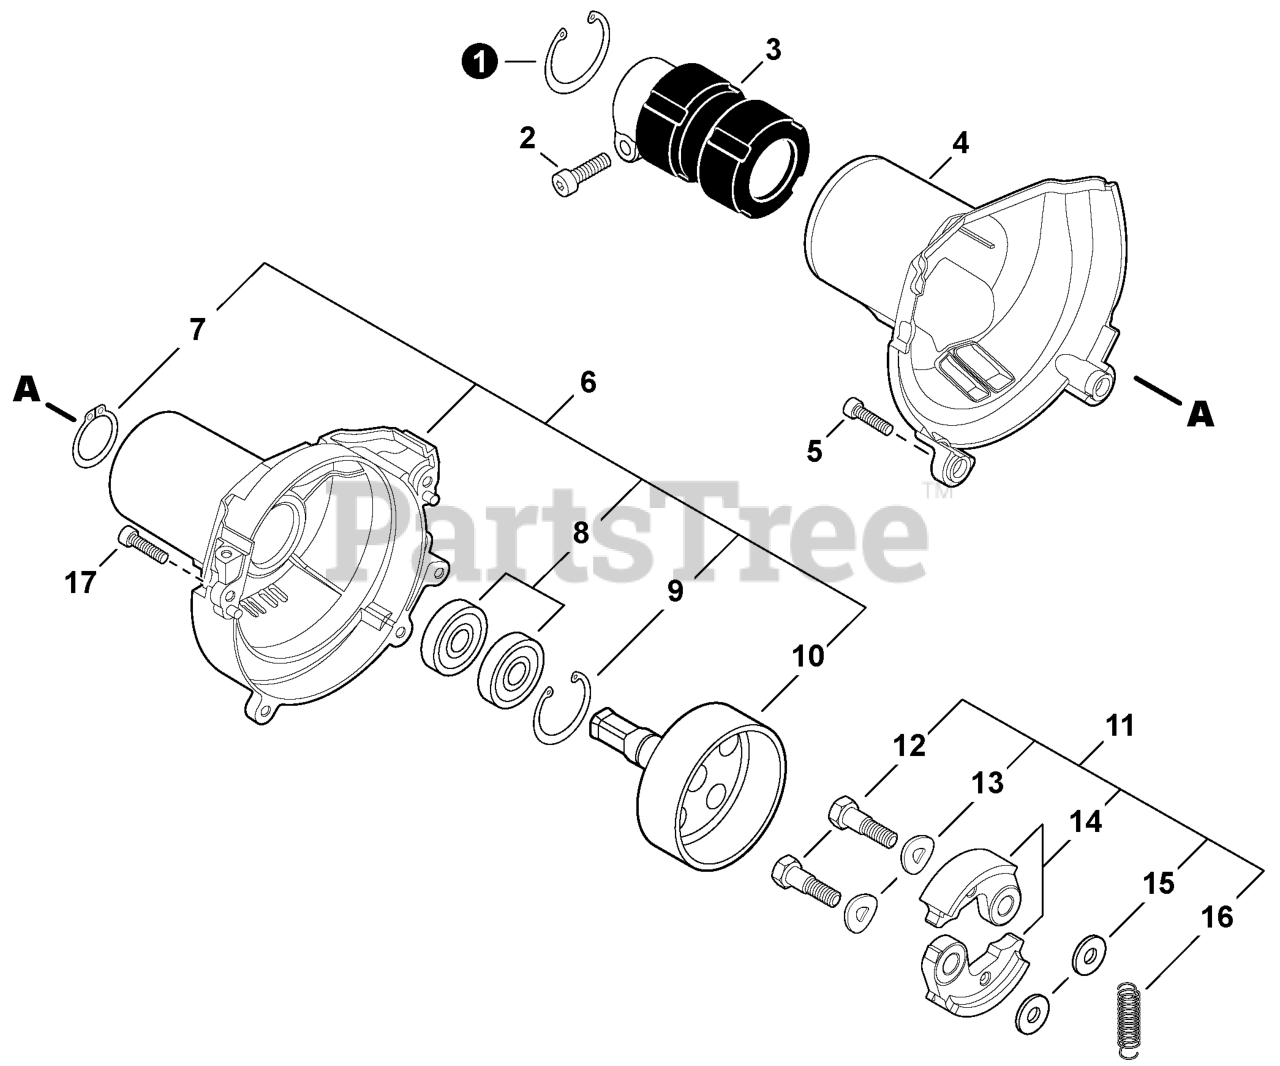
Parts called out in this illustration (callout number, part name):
1	RING, SNAP 42
2	BOLT, TORX 5x25
3	HOLDER, MAIN PIPE
4	PROTECTOR, FAN COVER
5	BOLT, TORX 5x20
6	COVER ASSY, FAN
7	RING, SNAP 12
8	BEARING, BALL 6001
9	RING, SNAP 28
10	DRUM, CLUTCH
11	CLUTCH ASSY
12	BOLT, CLUTCH 8x7.9xM6
13	WASHER, SPRING 8.5x16x0.5
14	SHOE, CLUTCH
15	WASHER 6.2x19x1.0
16	SPRING, CLUTCH
17	BOLT, TORX 5x16
